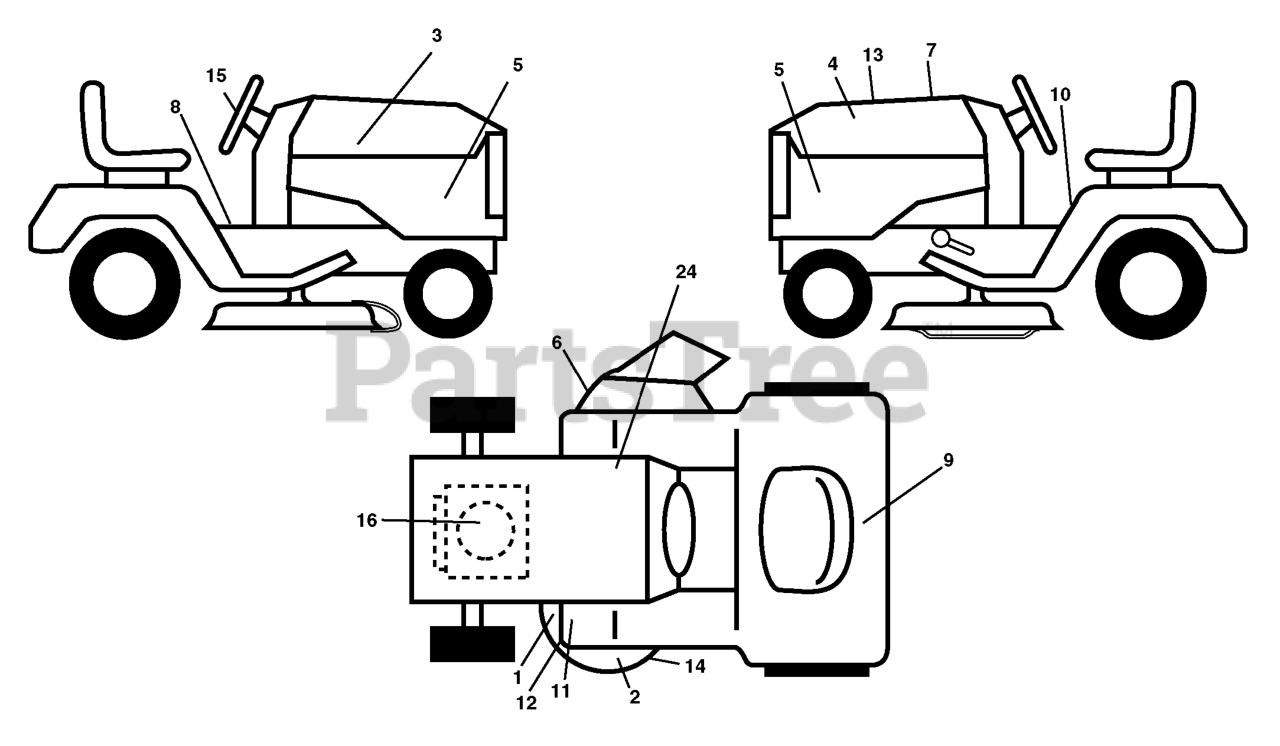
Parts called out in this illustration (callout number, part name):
1	DECAL CLUTCH/BRAKE
2	DECAL, MOWER HEAVY DUTY
5	DECAL.PANEL
6	DECAL.WARN.KEEP.HAND.AWAY
7	DECAL HOOD CUST. RESP.
9	DECAL.FENDER
11	DECAL.FOOTREST.YTGT.ENG.BRAKE.
12	DECAL.MOWER
13	DECAL. RPLMNT
14	DECAL.SCHEMATIC.DECK
15	DECAL.STEERING.HUSQ.BLUE
16	DECAL.ENGINE
24	DECAL BTRY SYMBOLS
